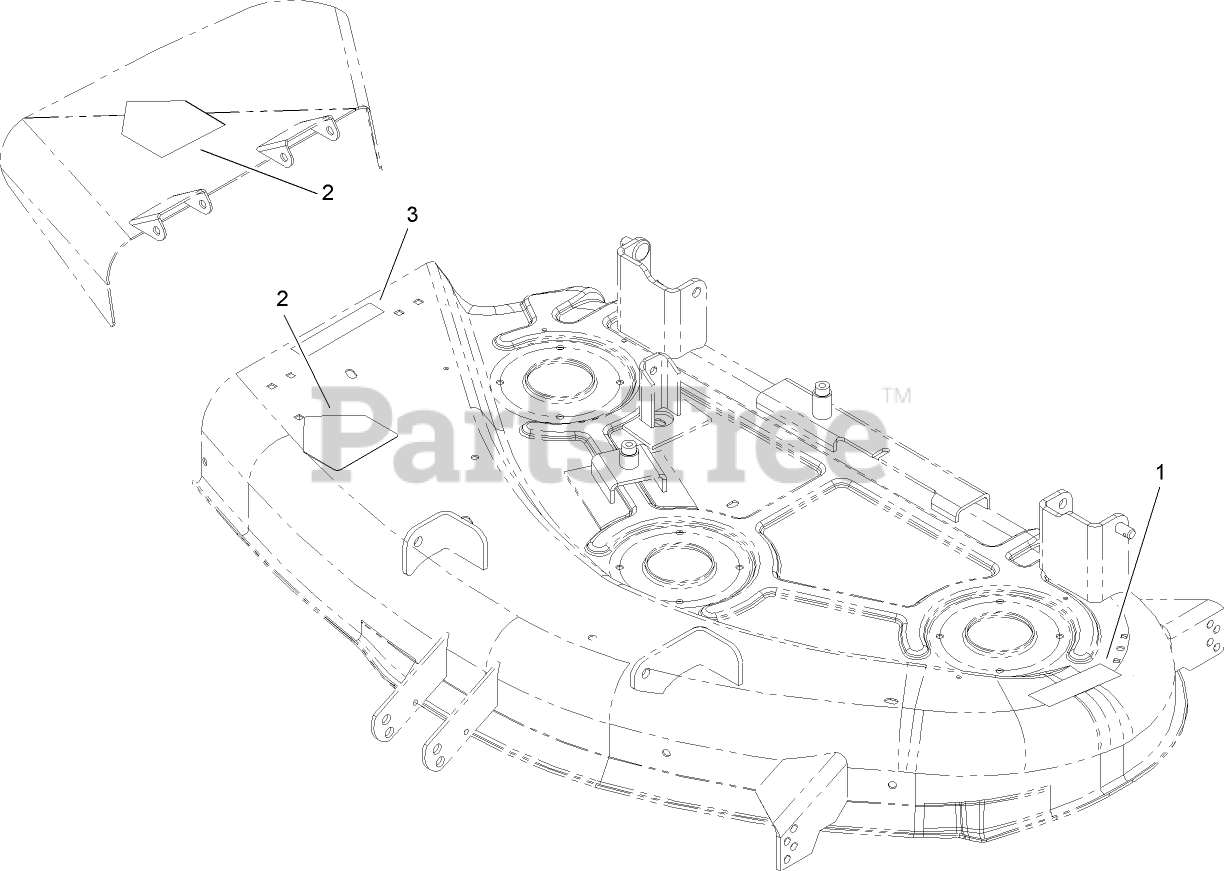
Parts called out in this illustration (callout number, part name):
1	DECAL-DANGER
2	DECAL-DANGER
3	DECAL-DANGER
